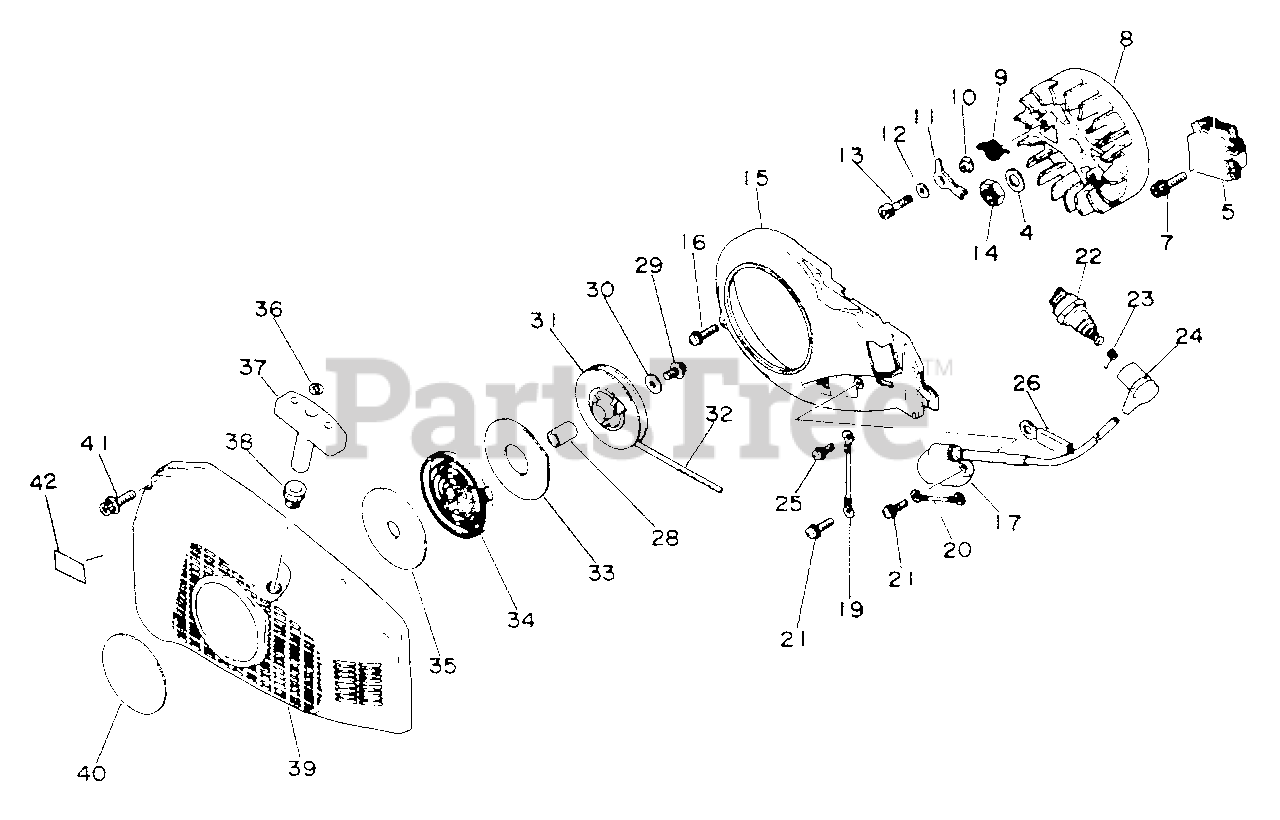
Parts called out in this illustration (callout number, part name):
4	LOCKWASHER
5	COIL, IGNITION
7	SCREW - 5X20
8	FLYWHEEL
9	SPRING, RETURN
10	SPACER
11	PAWL, STARTER
12	WASHER - 5
13	SCREW - 5X20
15	SHIELD, FAN
16	SCREW - 4X20
17	COIL, IGNITION
19	LEAD
20	LEAD
21	SCREW - 4X20
22	SPARK PLUG -- BPM-7A
23	TERMINAL, SPARK PLUG CAP
24	CAP, SPARK PLUG
25	SCREW - 4X12
29	SCREW - 5X10
30	WASHER - 5
31	REEL, ROPE
32	ROPE, STARTER - 4X950
33	PLATE, STARTER
34	SPRING, REWIND
35	PLATE, STARTER
36	RING, RETAINING
37	GRIP, STARTER
38	GUIDE, ROPE
39	CASE, STARTER
40	LABEL - ECHO
41	SCREW - 5X20
42	LABEL - NOISE
